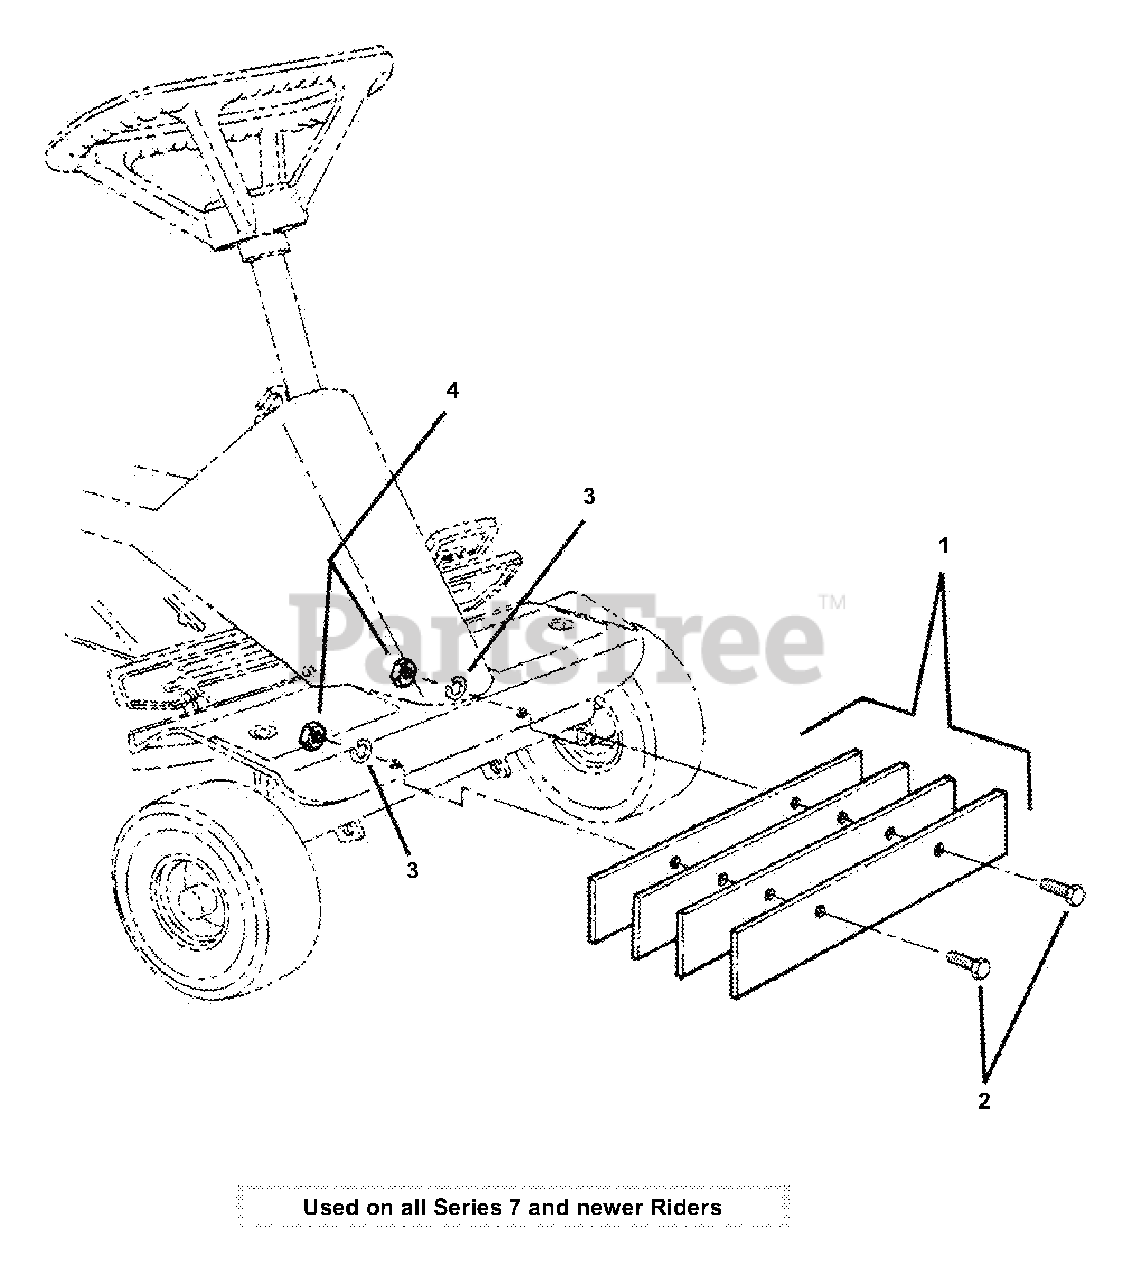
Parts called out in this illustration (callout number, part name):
1	WEIGHTS
2	SCREW, 5/8-11 x 1-1/4" Hex Head Cap
3	WASHER, 5/8" Split Lock
4	NUT, 5/8-11 Hex
